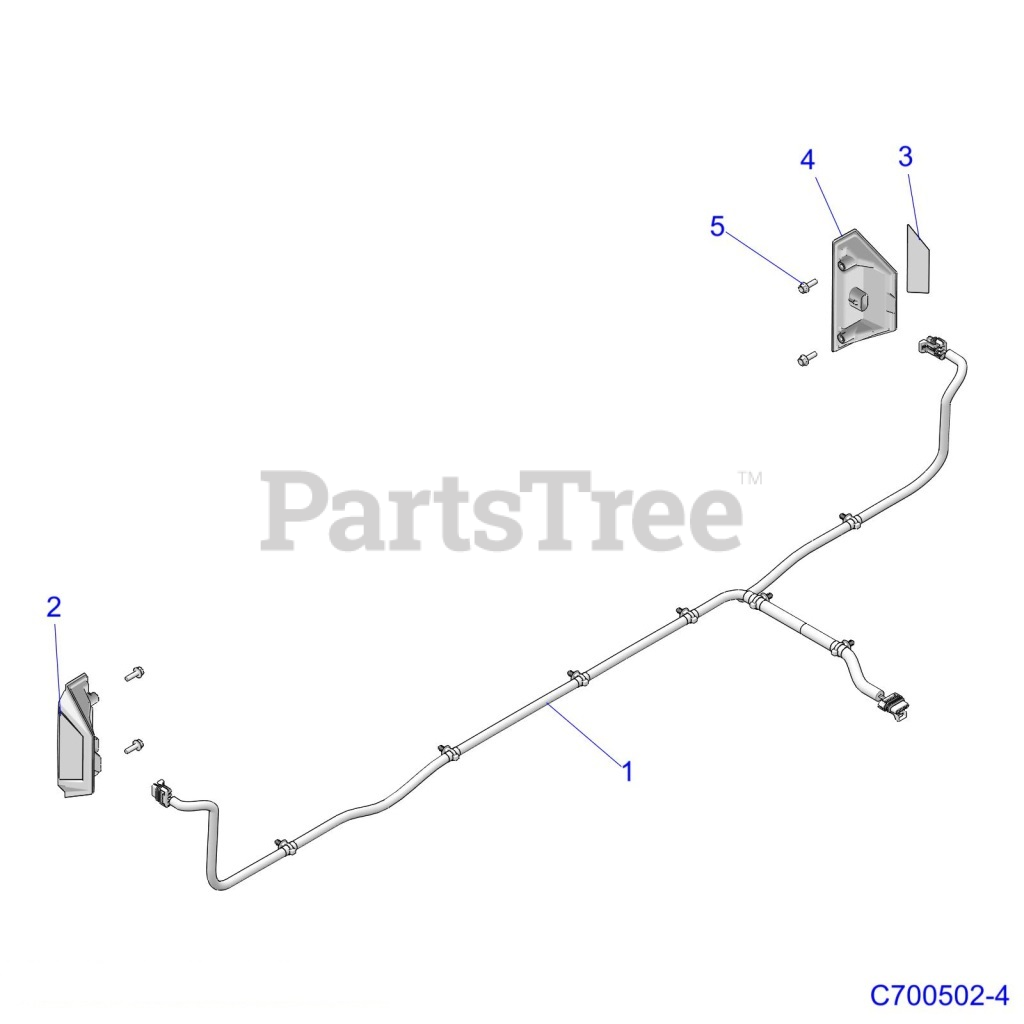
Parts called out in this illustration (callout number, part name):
1	HARNESS,BOX
2	ASM-TAILLIGHT,W/DECAL
3	DECAL-RED REFLECTOR
4	ASM-TAILLIGHT
5	SCR-HXFL-M6X1.0X20 8.8 RIE
